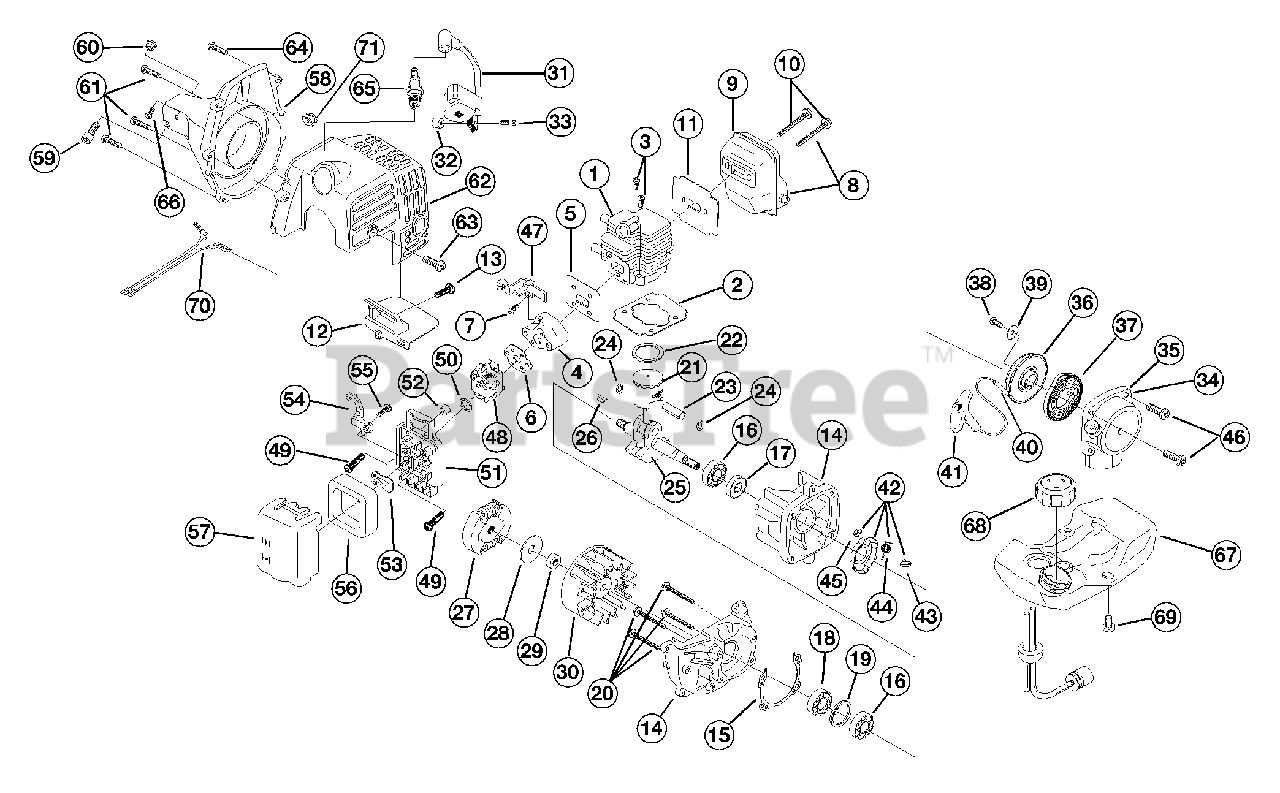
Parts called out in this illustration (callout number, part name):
2	Cylinder Base Gasket
5	Insulator Gasket
6	Carburetor Gasket
7	Screw and Washer
8	Muffler Assembly
11	Muffler Gasket
12	Muffler Plate
14	Crankcase Service Assembly
15	Crankcase Gasket
25	Crankshaft
28	Clutch Washer
30	Flywheel Assembly
31	Module Assembly
33	Screw
34	Recoil Assembly
35	Recoil Case
36	Recoil Pulley
37	Recoil Spring
41	Pull Handle
42	Pulley Assembly
45	Retaining Ring
47	Throttle Bracket
48	Carburetor
51	Air Cleaner Assembly
53	Choke Plate
54	Choke Lever
57	Air Cleaner Cover
58	Clutch Housing Assembly
62	Engine Cover
67	Fuel Tank
68	Fuel Cap Assembly
70	Lead Wire Assembly
